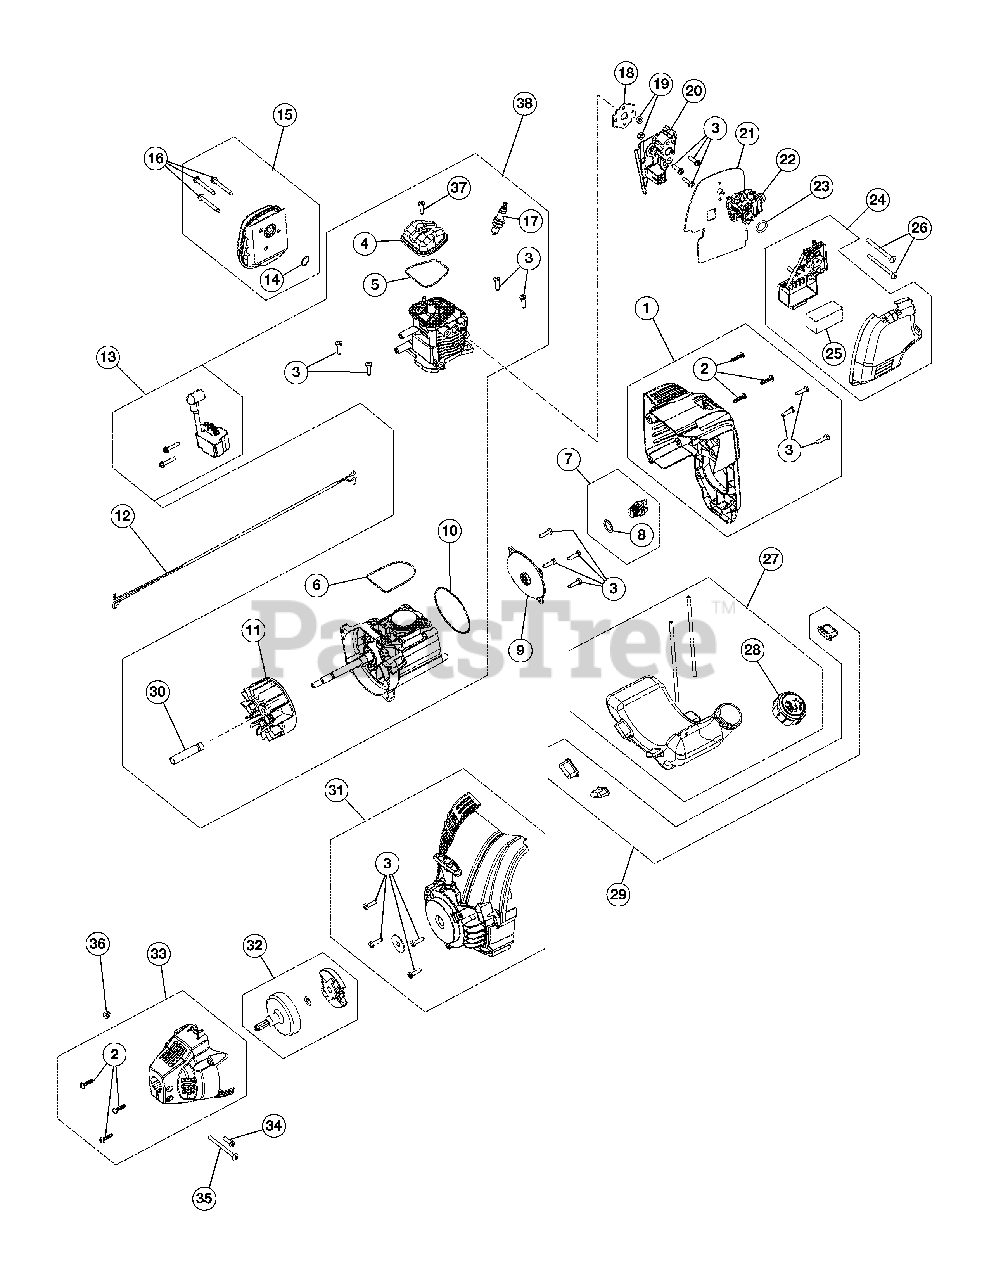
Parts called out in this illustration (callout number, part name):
1	Engine Cover Assembly (Incl. Ref No. 2 & 3)
2	Cover Screw
4	Rocker Cover
5	Rocker Cover O-Ring
6	Cylinder O-Ring
7	Oil Plug (Incl. Ref No. 8)
8	Oil Plug O-Ring
9	Crankcase Cover
10	Crankcase Cover O-ring
11	Flywheel Assembly
12	Lead Wires
13	Module Assembly
14	Muffler Gasket
15	Muffler Assembly (Incl. Ref No. 14 & 16)
16	Muffler Screw
17	Spark Plug
18	Insulator Gasket
20	Insulator
21	Carburetor Gasket
22	Carburetor w/Primer
24	Air Cleaner Cover Assembly (Incl. Ref No. 25)
25	Air Filter
27	Fuel Tank Assembly w/Fuel Lines (Incl. Ref No. 28)
28	Fuel Cap
29	Fuel Tank Pads
30	Spacer
31	Starter Housing Assembly (Incl. Ref No. 3)
32	Clutch Assembly
33	Clutch Cover (Incl. Ref No. 2)
34	Anti-Rotation Screw
35	Clamp Screw
36	Nut
37	Rocker Cover Screw
38	Shortblock Assembly (Incl. Ref No. 3-8, 10 & 17)
